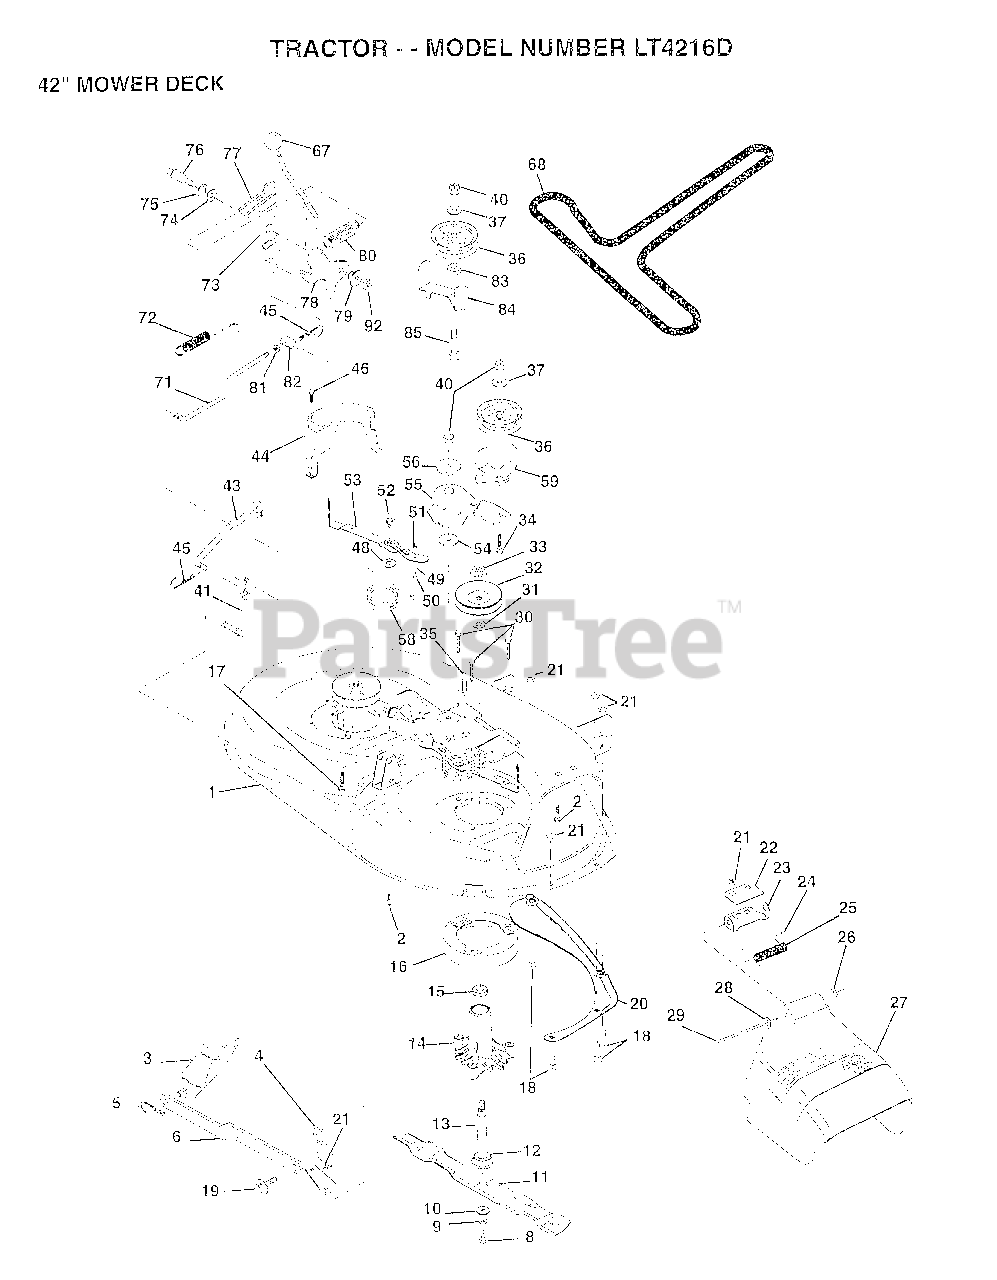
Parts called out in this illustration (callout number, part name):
1	DECK.WELD.42.
2	BOLT
3	BRKT ASM SWAY BAR
4	BRKT DECK SW BAR
8	BLADE BOLT
10	WASHER.HARD.BLADE
11	"BLADE.42"" HIPERF"
12	BEARING.BALL
14	HSG ASM MANDREL
15	BEARING
16	STRIPPER RND MWR
17	BOLT RDHD 3/8-16
18	BOLT
19	BOLT SHD 5/16-18
22	STIFFENER BRKT
23	DEFLECTOR BRKT
24	CAP-SLEEVE LT
25	SPRING TORSION
26	NUT PUSH M
27	DEFLECTOR.SHIELD
28	WASHER
29	HINGE ROD
31	WASHER
34	BOLT
35	XMAS TREE FASTNER
36	FLAT IDLER PULLEY
37	WASHER
41	PIVOT ROD
43	ROD CLUTCH W/NIBS
44	GUARD MAND LH BLK
45	RETAINER M
46	SCREW.1/4-20X5/8
48	HARD SMALL WASHER
50	SHOULDER BOLT
51	LOCKNUT
52	BOLT.SHLD.5/16-18
53	BRAKE PAD ARM ASM
54	HARDENED WASHER
56	SPACER RETAINER
58	SPRING TORSN BRAK
59	GUARD IDLER TUV
67	KNOB T(3/8 HOLE)
68	BELT.V.T-PATH
71	ROD CLUTCH 38/42
72	RETURN SPRING
73	CLUTCH ARM SECOND
74	WASHER
75	RING
76	SHOULDER BOLT
77	SPRING KEEPER
79	BUSHING
81	NUT
82	TRUNION ADJ
83	WASHER
85	BOLT
92	NUT
